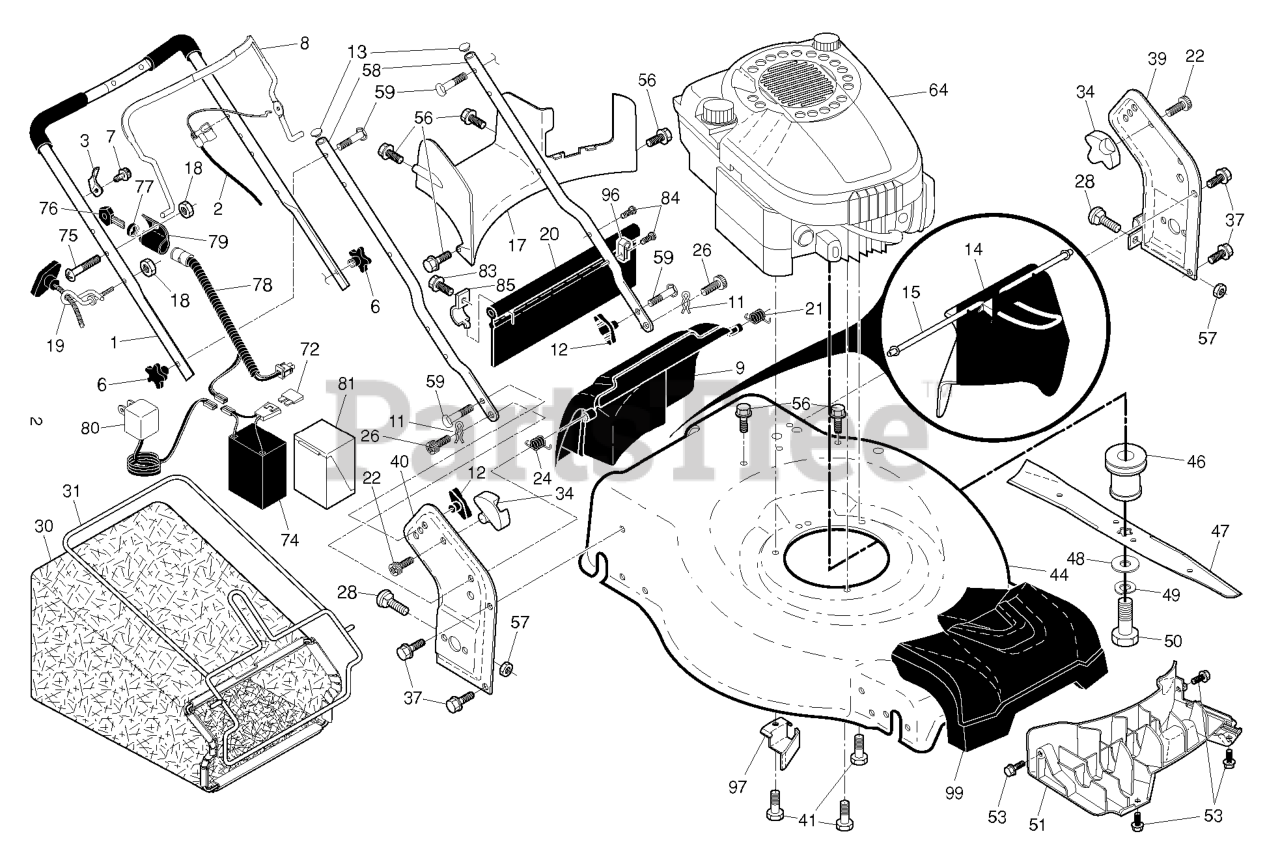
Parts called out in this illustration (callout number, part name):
1	HANDLE.ASM.UP.BS.AW2.GRIP.498
2	CABLE.MZR.50.SNAP-IN
3	BRACKET.UPSTOP.RT
6	KNOB.HANDLE.PLASTIC.STAR.BLACK
8	BAIL.CONTROL.MZR.BS.ORANGE
9	DOOR.REAR.ASM.22+.HUSQ.FG/RGD
11	COTTER.HAIRPIN.DOOR/HANDLE.PIV
12	KNOB, DEFLECTOR
13	PLUG.PLASTIC.7/8".14-20.GAUGE
14	DEFLECTOR.CHUTE.22+REAR
15	HANDLE DEFLECTOR.22+REAR
17	BAFFLE.REAR.22+RGD.AWD.PLASTIC
18	NUT
19	RB GUIDE.ROPE.STD.BLK.ZIN WSL
20	SKIRT.REAR.22PLUS.RGD.LW(2 2MC
21	SPRING.LH.BLACK
22	SCREW.PAN.HEAD.#10
24	SPRING.RH.GRAY
26	SCREW,DOOR/HANDLE.PIVOT
28	BOLT
30	GBAG.A3610247T.SILV.HUSWT.BLUE
31	RB FRAME.GBAG.22PLUS
34	BRACKET.GRASSBAG.ATTACHING.BLK
37	BOLT.5/16HEX.WHS.HD
39	BRACKET.ASM.HNDL.LT.22+.GREY
40	BRACKET.ASM.HNDL.RT.22+.GREY
41	BOLT 3/8-16X1-1/8
44	HOUSING.22+.RWD.HD.WO/PORT.ORN
46	ADAPTER.BLADE.25MM.3MPH
47	BLADE.22+.PREMIUM/PREC.FGD/RGD
48	WASHER,HARDEN
49	LOCKWASHER
50	SCREW, HEX HD 3/8-24 X 1-3/8
51	BAFFLE.FRONT.22+PLASTIC.(2 2)
53	SCREW.HI-LO.5/16 X.75
56	SCREW.HX.13X.750
57	NUT.FLANGE.5/16
58	HANDLE.LOWER.22+BT.2PC.GRY
59	BOLT, HANDLE 5/16-18X1.75
74	BATTERY.12V.22+RWGD
75	SCREW.(COMBINATION CONTROL)
76	KEY.MOLDED
77	NUT.CAP.SNAP-ON.KEY START
78	HARNESS.22+.BATTERY.RWGD
79	HOUSING.WIRING.HARNESS
80	RP CHARGER.12V.0.1A
81	BOX.BATTERY.22+RGD.GREY
83	TAPPING SCREW
84	FASTENER.PUSH.O.250X0.783
85	BRACKET.SKIRT.22+.BZP
96	CLIP.CABLE.BLK
97	BRACKET.BELT.GUIDE.22+.BZP
99	COVER.ASM.FRONT.SHROUD.HUSQ.
